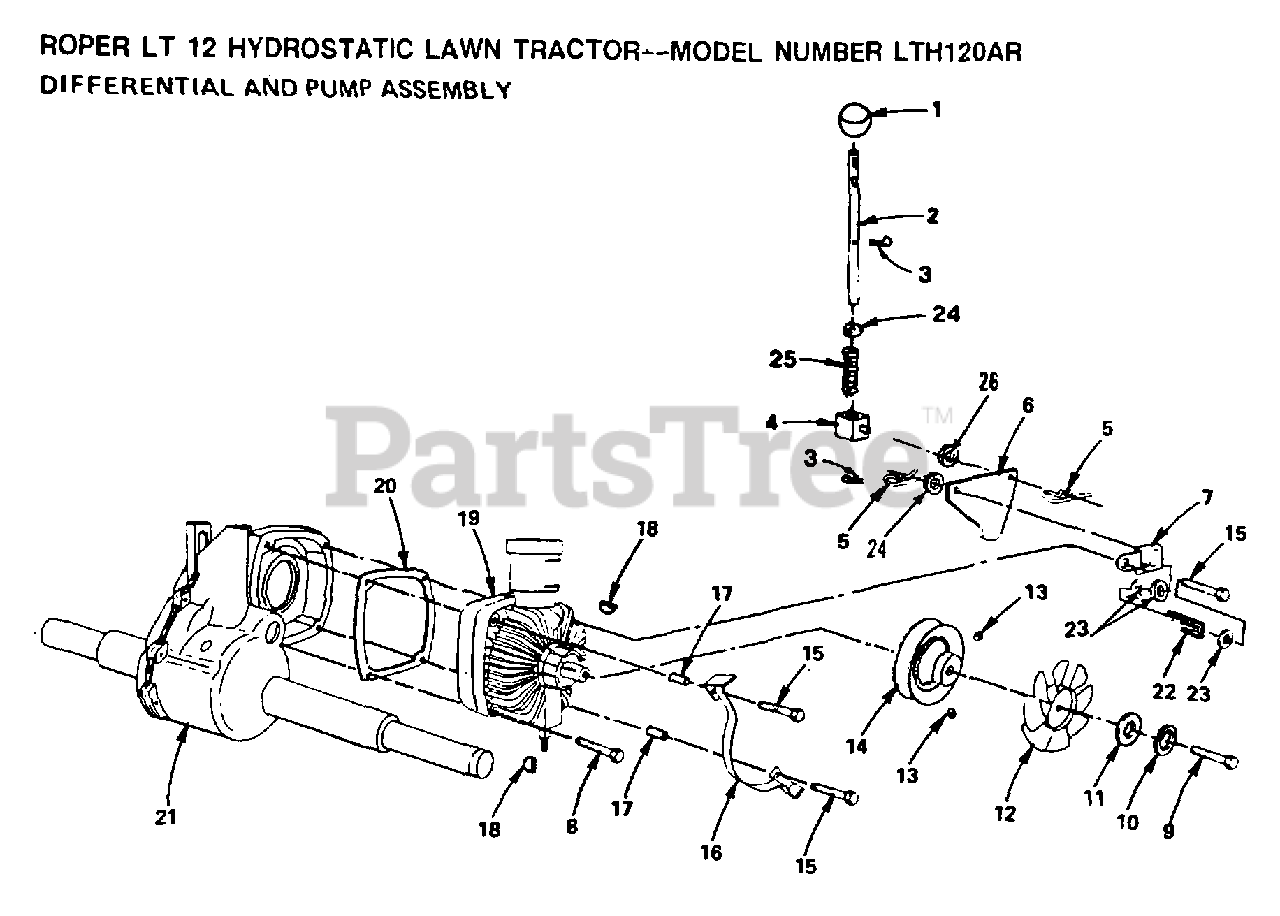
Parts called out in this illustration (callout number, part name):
1	KNOB T(3/8 HOLE)
3	COTTER PIN
4	TRUNION HYT
5	SPRING.RETAINER
6	CONTROL COAST HYT
7	BRKT ASSEM HYT
8	BOLT - HEX 3/8 - 16 X 3
9	BOLT LT
10	LOCKWASHER
11	WASHER
12	FAN HYDRO HYT
16	KIT CENTERING Y
18	KEY T
19	PUMP HYDRO HYT
20	GASKET HYDRO HYT
23	WASHER
24	WASHER T
25	SPRING GTV
26	WASHER
